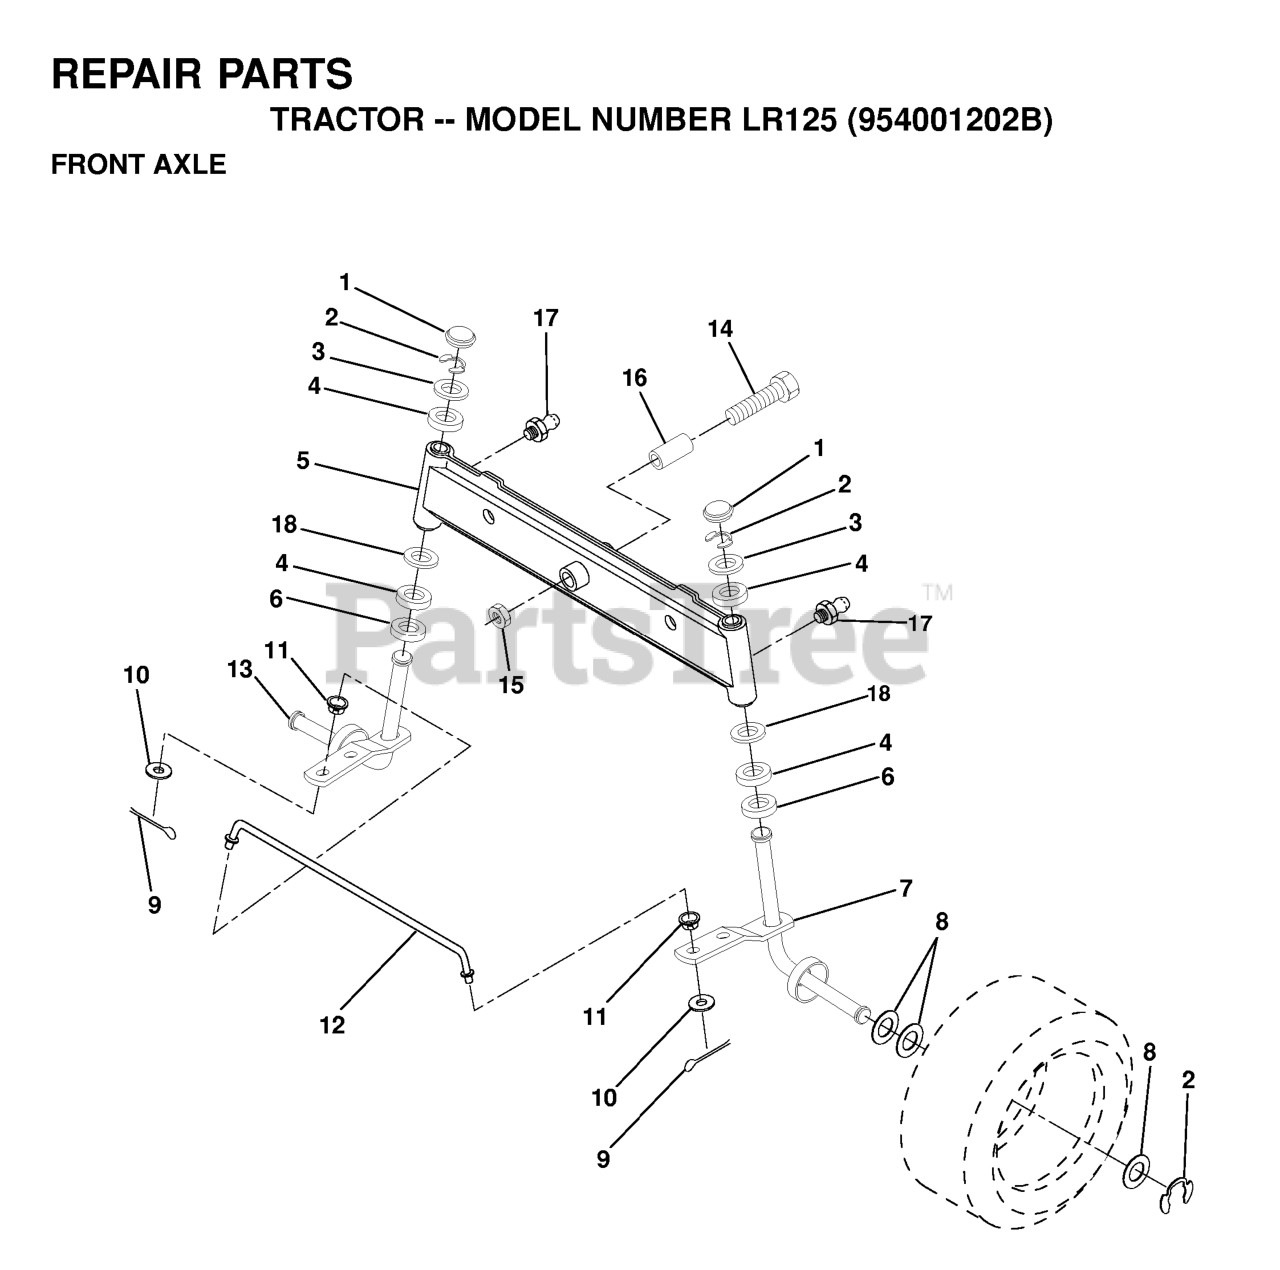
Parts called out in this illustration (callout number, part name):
1	CAP.SPINDLE.BLACK
4	BRNG T
6	THRUST WASHER
7	SPINDLE ASSY RH NLA
9	COTTER PIN
10	WASHER
11	BUSHING.DRAGLINK (2 2)
12	TIE ROD
13	SPINDLE ASSY LH
14	Bolt, Hex Head 5/8-11 x 3-1/2
15	NUT-LOC,FLANGE LT
16	BEARING
17	ZERK M
